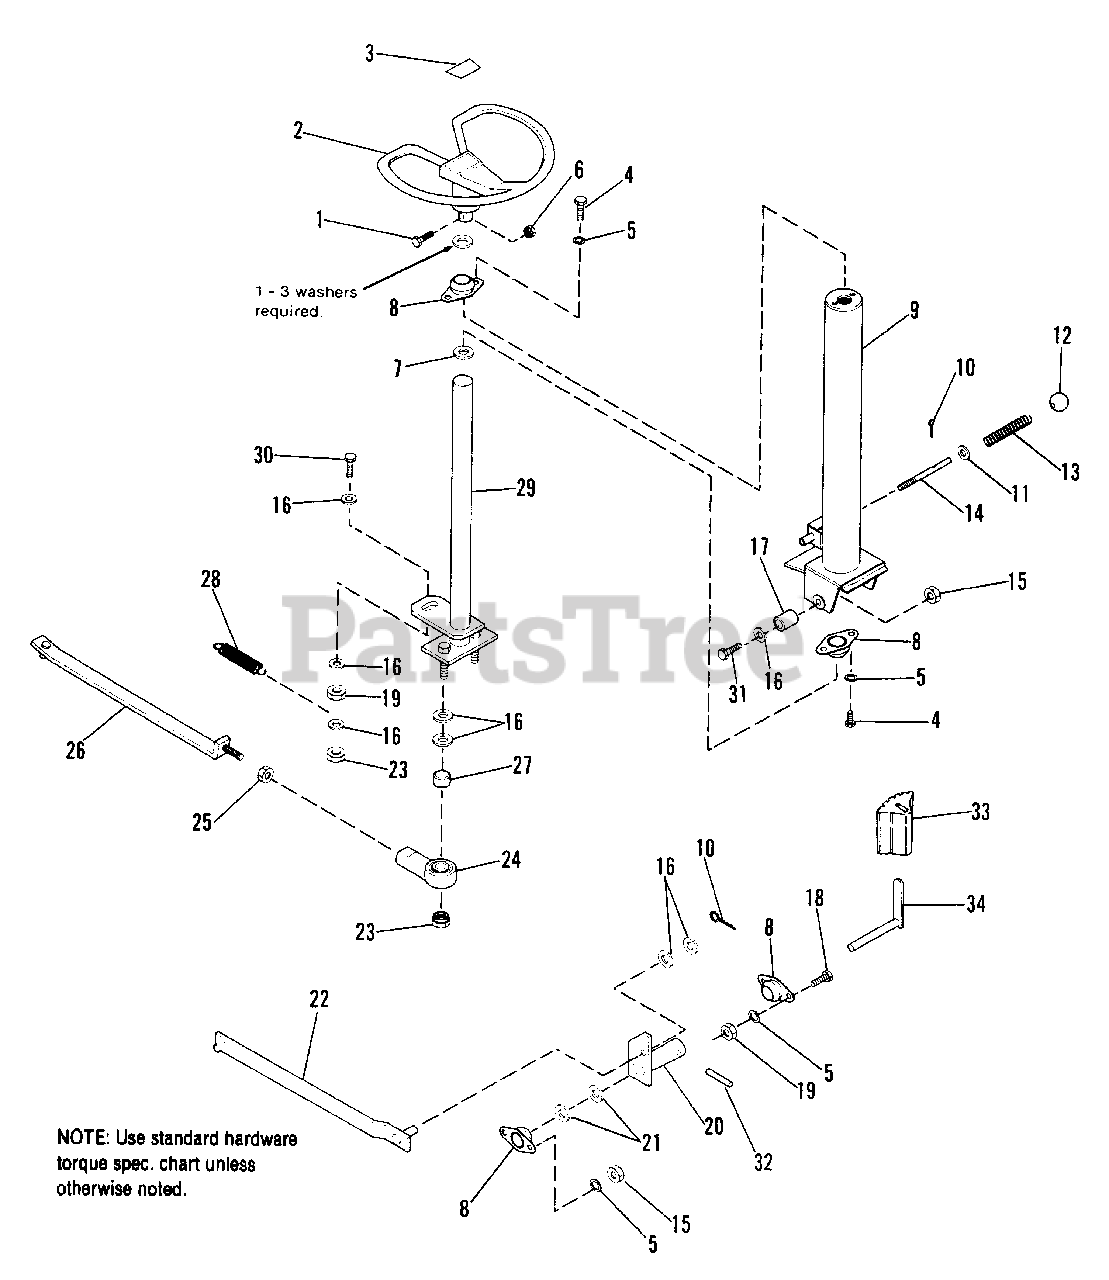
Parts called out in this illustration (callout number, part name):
1	SCREW, Taptite, 3/8-16 x 1-1/2
2	WHEEL, Steering
3	INSERT, Steering Wheel
4	CAPSCREW, Hex, 5/16-18 x 1/2
5	LOCKWASHER, Spring, 5/16
6	LOCKNUT, Hex, 3/8-16
7	WASHER, Plain
8	BEARING, Flanged
9	STEERING COLUMN ASSY.
11	WASHER, Plain
14	ROD, Latch
15	LOCKNUT, Hex, Flanged, 5/16-18
16	WASHER, Plain
18	CAPSCREW, Hex, 5/16-18 x 3/4
19	NUT, Hex, 5/16-18
20	CLUTCH ARM ASSY.
21	WASHER, Plain
22	LINK ASSY., Clutch, Front
23	LOCKNUT, Hex, 5/16-18
25	NUT, Hex, 5/16-24
26	LINK ASSY., Steering
29	SHAFT ASSY.
30	CAPSCREW, Hex, 5/16-18 x 1-1/4
31	CAPSCREW, Hex, 5/16-18 x 1
33	PAD, Non-Skid, Pedal
34	CLUTCH PEDAL ASSY.
